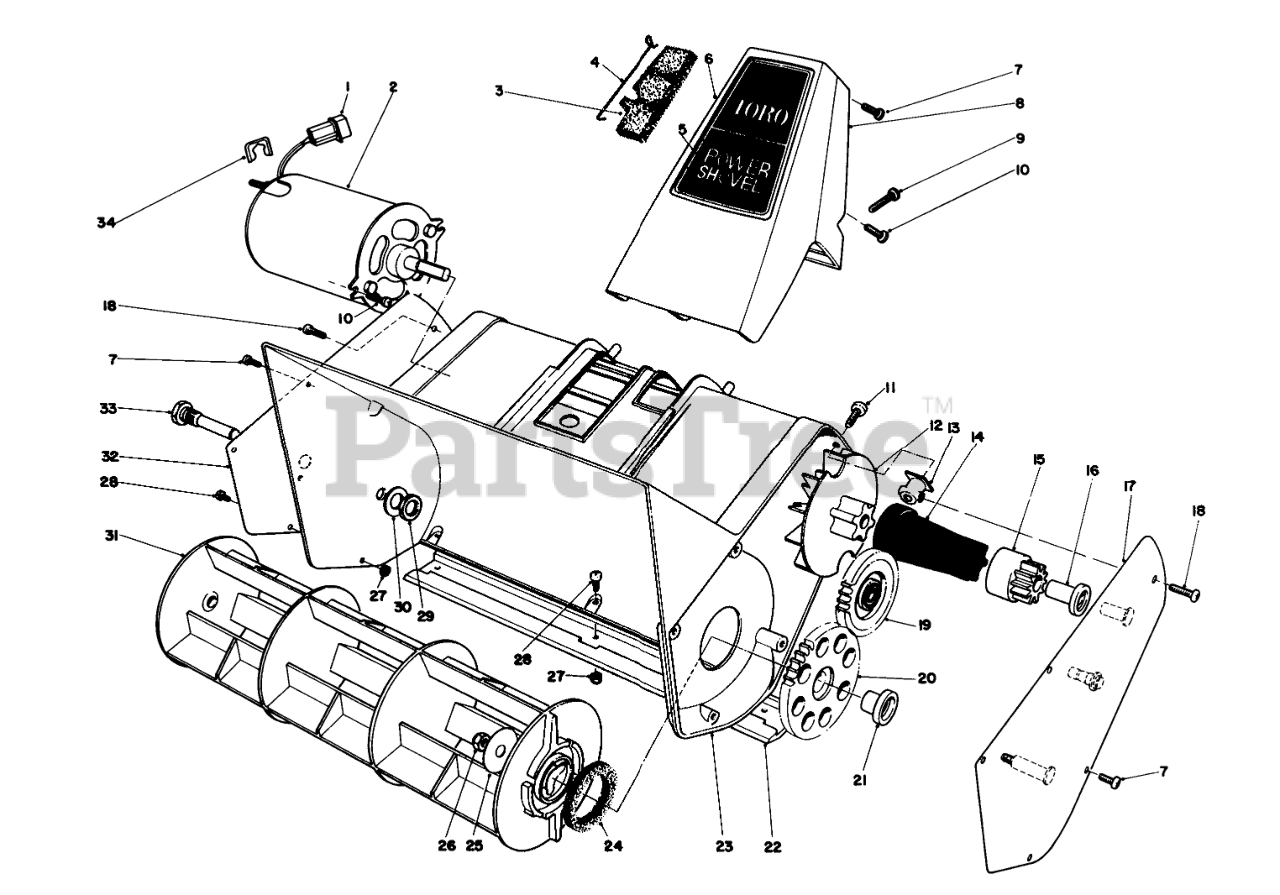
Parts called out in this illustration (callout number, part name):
1	HSG PIN CONNECTOR
2	MOTOR, POWER SHOVEL
3	ATTACHING BRKT R
4	RETAINER - FILTER
5	HANDLE SUPT DECAL
6	HANDLE SUPPORT, FRONT
7	SCREW-PPH
8	Handle Support-Back
9	Screw-Pan Head
10	SCREW-PPH
11	#10-10X3/4 PLASCREW
12	FAN, POWER SHOVEL
13	MOUNTING BLOCK
14	DRIVE COUPLING
15	Drive Gear (Incl. Ref. #16)
16	SAFETY LATCH
17	Gear Carrier
18	Screw
19	IDLER GEAR ASM
20	Rotor Gear Assembly (Incl. Ref. #21)
21	BUSHING, ROTOR GEAR
22	Scraper
23	Housing
24	FELT WASHER
25	ROTOR WASHER
26	NUT-LOCK, NI
27	NUT-LOCK
28	SCREW-PPH
29	NUT-LOCK, CONE
30	WASHER-FLAT
31	ROTOR
32	RT. SIDE COVER (RAW)
33	ROTOR PIN
34	Strain Relief
